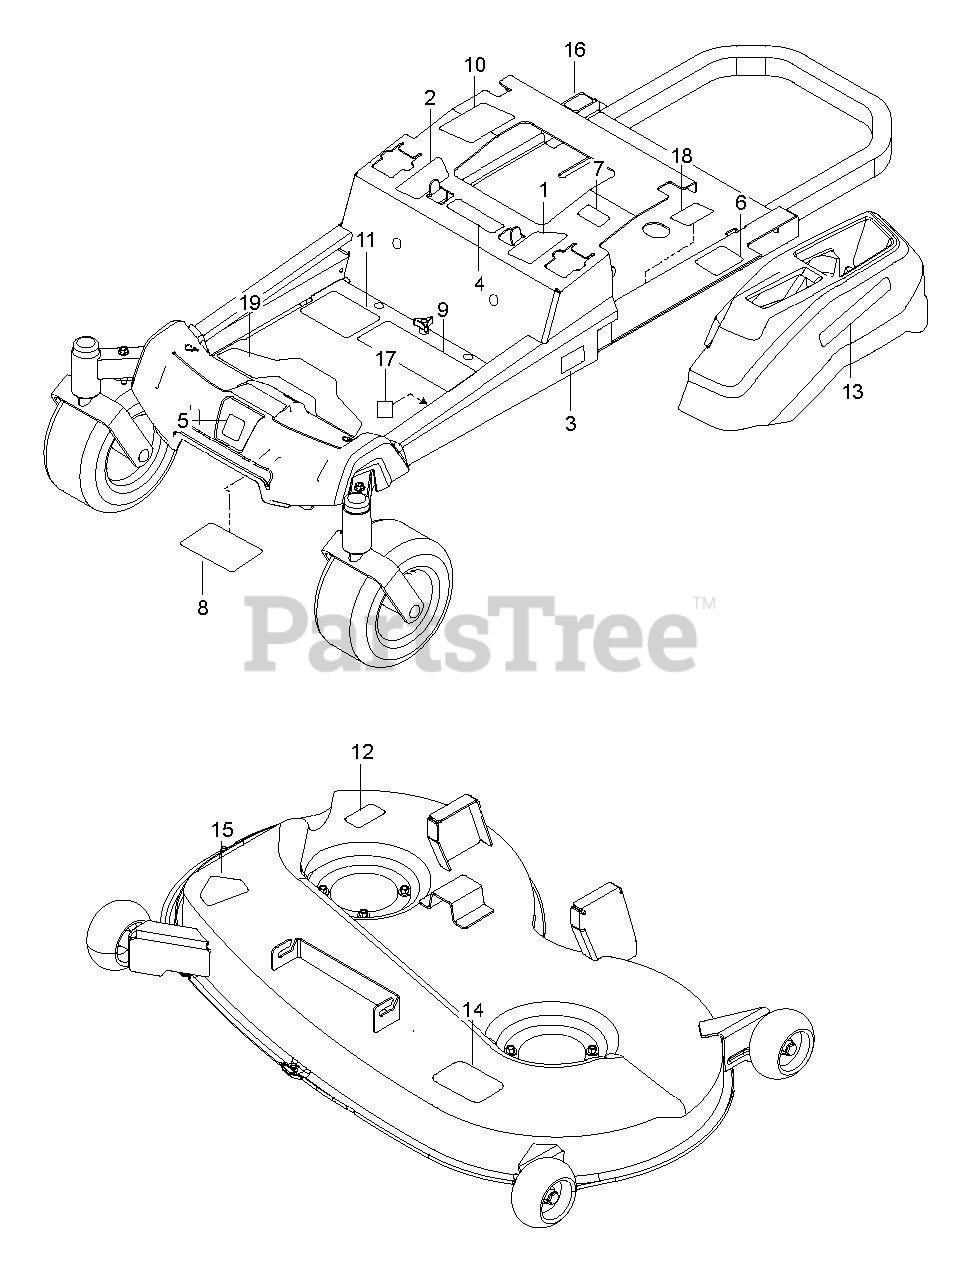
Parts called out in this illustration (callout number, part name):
1	DECAL.ZTR.RZ.THRTL/PRKBRK.V2.L
2	DECAL.ZTR.RZ.THRTL/PRKBRK.V2.R
3	DECAL.ZTR.SIDERAIL.Z246.HUSQ
4	EURO DECAL-BATTERY WARNIN6
5	DECAL.BADGE.55MM.CROWNH.HUSQ
6	DECAL, DO NOT TOW
7	DECAL, EXITING MOWER
8	DECAL, SERVICE
9	DECAL.ZTR.WARNING.SMARTIGNITIN
10	DECAL.WARNING.CUST.RESP.E85.
11	DECAL.ZTR.STARTINSTRCT.CHOKE15
12	DECAL.DECK.6MIL./DEF.SHLD.WARN
13	DECAL.HUSQVARNA.210MM
14	DECAL, BELT ROUTING
15	DECAL, DECK DEFLECTOR, WARNING
16	DECAL CERTIFICATION DECAL EMCC
17	DECAL.80.DBA.AUSTRALIA
18	DECAL.EPA.EMISS.LABEL.ZTR.18
19	PAD.RZ.FOOTREST.PLATE
